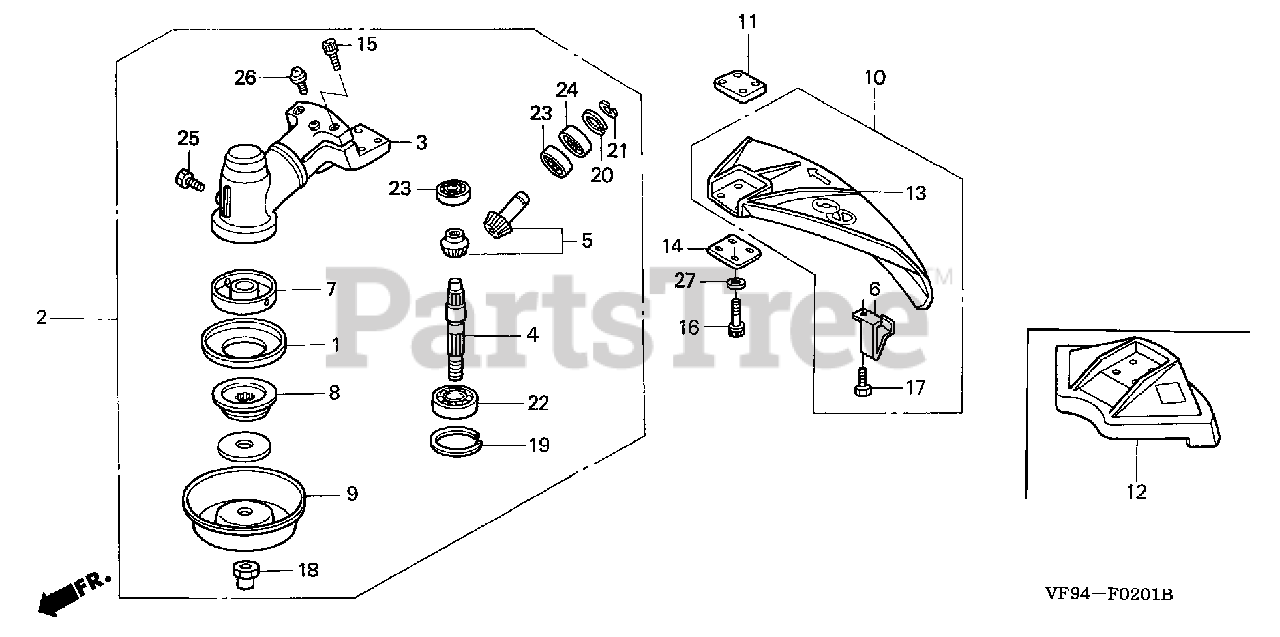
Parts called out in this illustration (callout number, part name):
1	GUARD, GRASS
2	CASE ASSY., GEAR
3	CASE, GEAR
4	SHAFT, GEAR
5	GEAR ASSY., BEVEL
6	PLATE, NYLON CUTTING
7	HOLDER A, BLADE
8	HOLDER B, BLADE
9	COVER, NUT
10	DEFLECTOR ASSY., GRASS
11	SPACER, DEFLECTOR
12	DEFLECTOR, GRASS
13	DEFLECTOR, GRASS
14	PLATE, DEFLECTOR
15	BOLT, SOCKET (5X20)
16	BOLT, SOCKET (5X30)
17	BOLT, SOCKET (5X15)
18	NUT, HEX. (10MM)
19	CIRCLIP (INNER) (28MM)
20	CIRCLIP (INNER) (26MM)
21	CIRCLIP (OUTER) (10MM)
22	BEARING, RADIAL BALL (6001LL)
23	BEARING, RADIAL BALL (6000)
24	BEARING, RADIAL BALL (6000Z)
25	BOLT, HEX. (6X8)
26	SCREW-WASHER (5X10)
27	WASHER, PLAIN (5MM)
